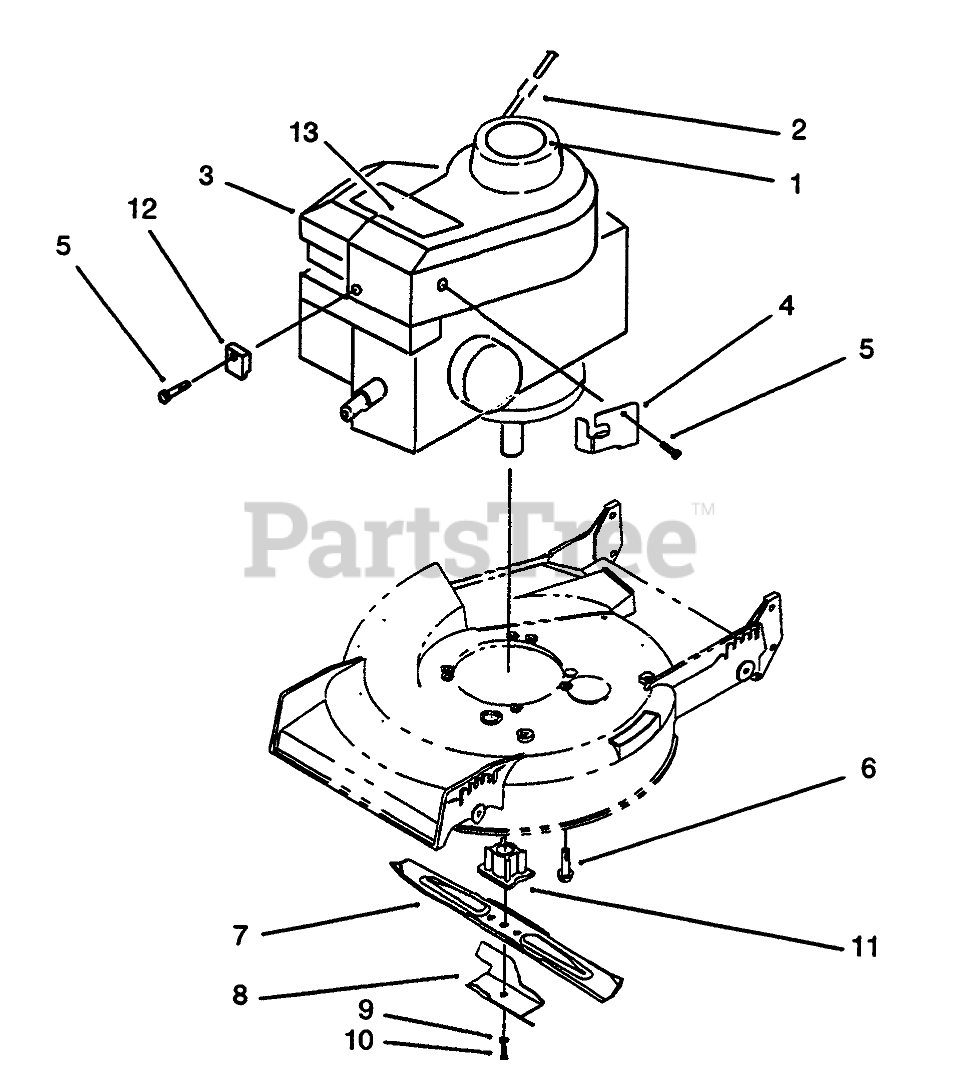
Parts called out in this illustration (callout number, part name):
1	Decal-Toro
2	STOP-ROPE
4	BRACKET - CABLE
5	CLAMP SCREW F/W ENGINE
6	SCREW-HWH
7	Blade
8	Accelerator
9	WASHER-LOCK
10	SCREW-BLADE
11	BLADE RETAINER
12	CASING CLAMP F/W ENGINE
13	DECAL - ENGINE
